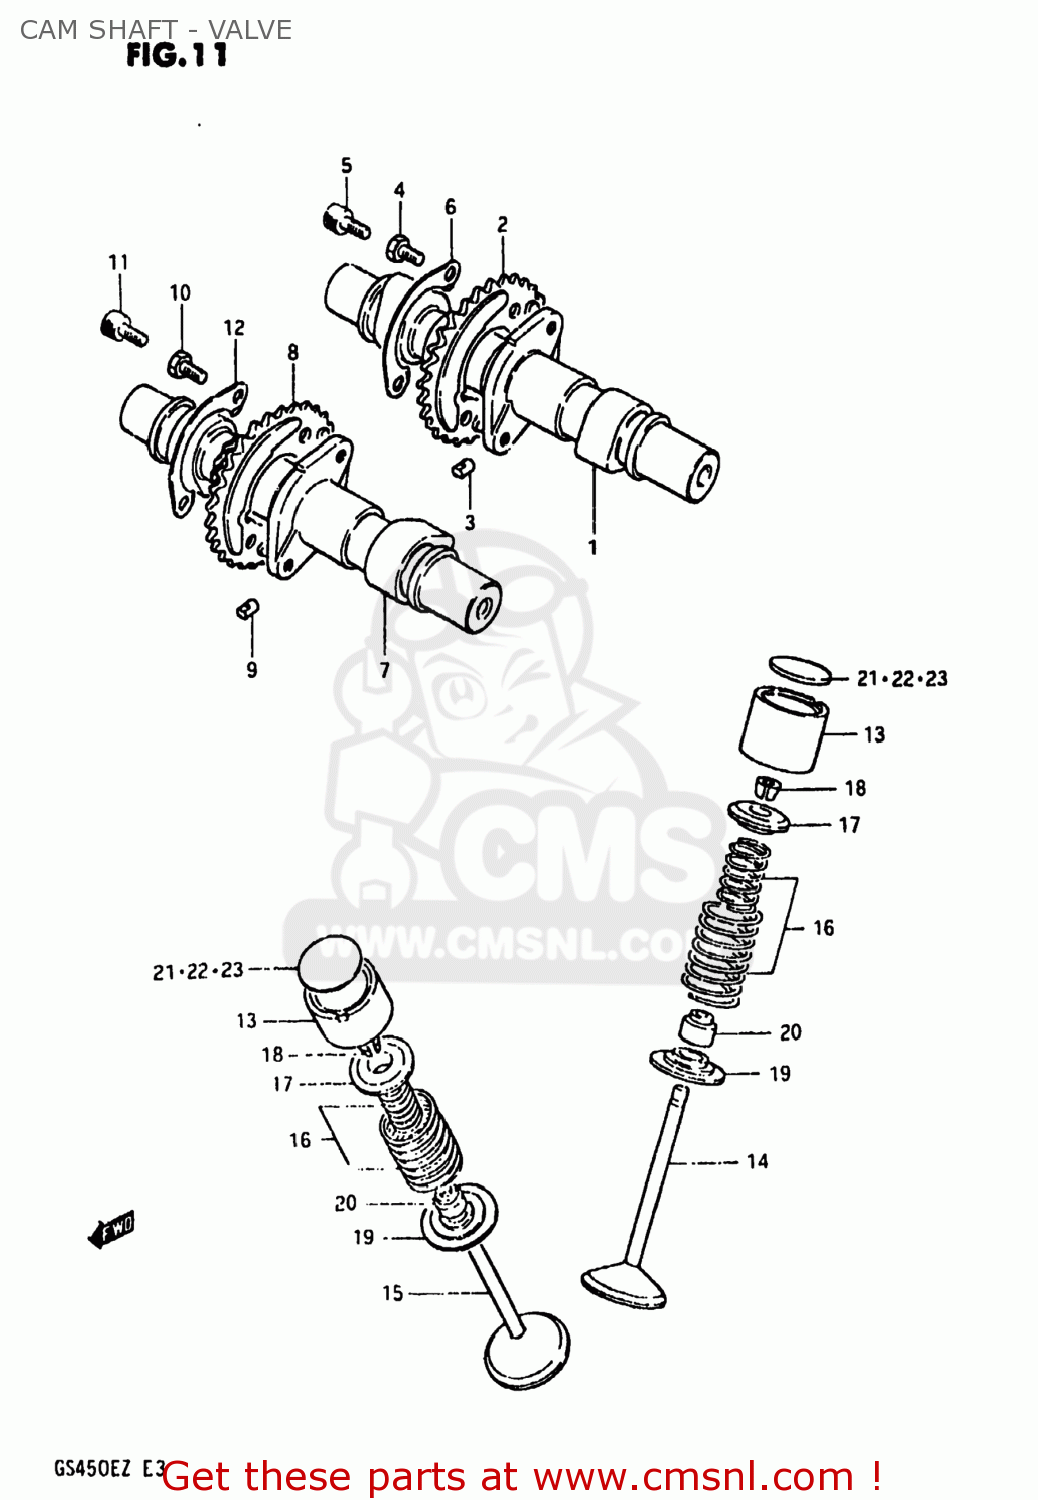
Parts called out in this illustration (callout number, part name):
1	CAMSHAFT
2	SPROCKET,CAMSHAFT
3	PIN,SPROCKET
4	BOLT(6X12.5)
5	BOLT 6X11
6	WASHER,CAM CHAIN SPROCKET
7	CAMSHAFT,EXHAUST
8	SPROCKET,EXHAUST CAMSHAFT
9	PIN,SPROCKET
10	BOLT(6X12.5)
11	BOLT 6X11
12	WASHER,CAM CHAIN SPROCKET
13	TAPPET
14	VALVE,INTAKE
15	VALVE,EXHAUST
16	SHIM,TAPPET
17	RETAINER,VALVE SPRING
18	COTTER VALVE
19	SEAT,VALVE SPRING
20	SEAL,OIL(7X14.4X9)
21	SHIM,TAPPET
22	SHIM,TAPPET
23	SHIM,TAPPET
24	SHIM SET,TAPPET
25	CASE
